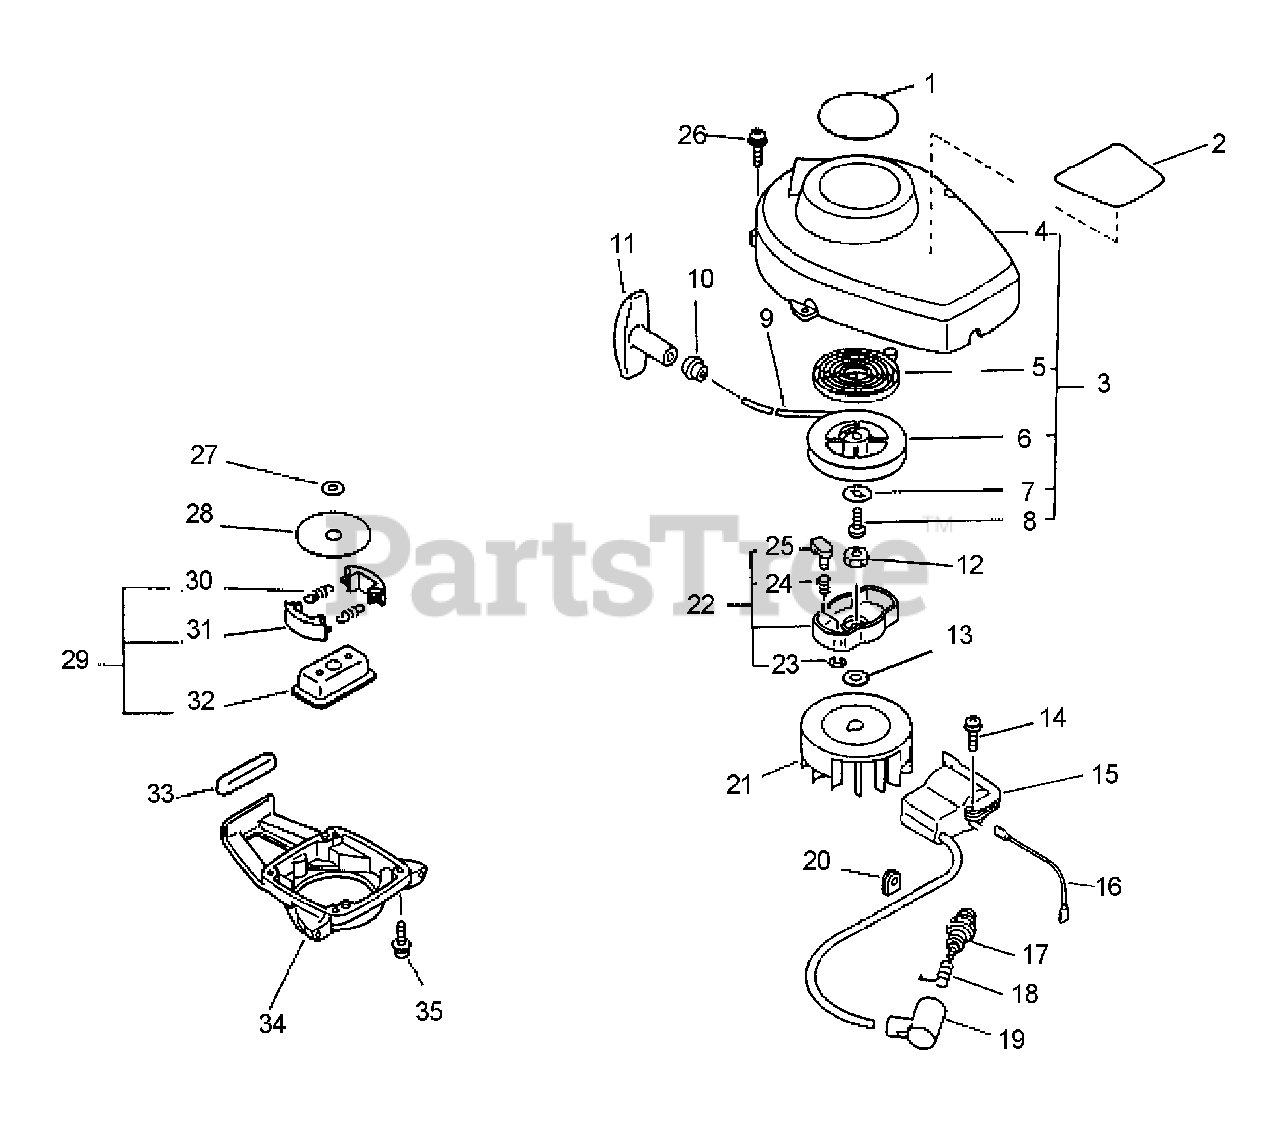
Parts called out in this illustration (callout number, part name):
1	LABEL, ECHO
2	LABEL, HC-1600
3	STARTER ASSY
4	CASE, STARTER
5	SPRING, RECOIL
6	REEL, ROPE
7	WASHER
8	SCREW
9	ROPE, STARTER
10	GUIDE, ROPE
11	GRIP, STARTER
13	WASHER, SPRING 8
14	SCREW 4×22
15	COIL, IGNITION
16	LEAD
17	SPARK PLUG - BPM7A
17	SPARK PLUG - BPM-7Y
17	SPARK PLUG - RCJ7Y
18	TERMINAL, SPARK PLUG
19	CAP, SPARK PLUG
22	STARTER PAWL ASSY
23	E-RING 4
24	SPRING, RETURN
25	PAWL, STARTER
26	BOLT 4×16
27	WASHER, CLUTCH
28	PLATE, CLUTCH
29	CLUTCH ASSY
30	SPRING, CLUTCH
31	SHOE, CLUTCH
32	HUB, CLUTCH
33	CUSHION, FUEL TANK
34	HOUSING, CLUTCH
35	SCREW 4×16
